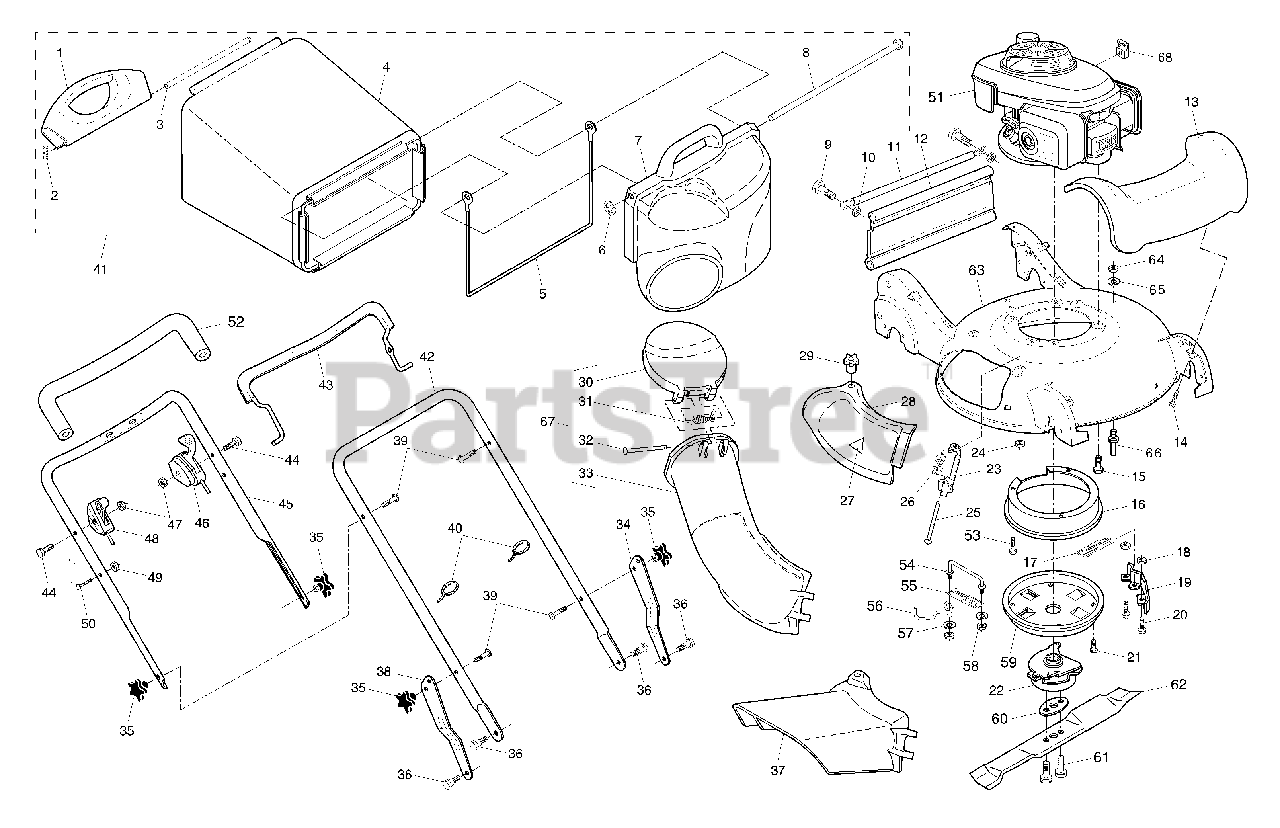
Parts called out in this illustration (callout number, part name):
1	Handle, Grassbag, Rear
2	Hairpin Cotter
3	Rod, Rear Handle, Grassbag
4	Grassbag
5	Frame, Grassbag
7	Door, Grassbag
8	Rod, Pivot
10	Nut, Hex
11	Tube, Rear Skirt
12	Skirt, Rear
13	Cover, Front
14	Screw, Hex Washer Head
15	Bolt, Engine Mounting
16	Belt Cover, Upper
18	Nut, Hex
19	Brake, Clutch
20	Bolt, Hex Head
21	Screw
22	Blade Brake / Clutch
23	Mounting Bracket, Mulcher Door
24	Nut, Hex
25	Rod, Hinge
26	Spring, Mulcher Door
27	Decal, Danger
28	Mulcher Door
30	Door, Discharge Chute
31	Spring, Door, Discharge Chute
32	Rod, Door, Discharge Chute
33	Discharge Chute, Plastic
34	Adjustment Bracket, Lower Handle, LH
35	Knob, Star
36	Bolt, Shoulder
37	Deflector, Discharge
38	Adjustment Bracket, Lower Handle, RH
39	Bolt, Handle
40	Wire Tie
41	Grassbag Assembly, Complete
42	Handle Assembly, Lower
43	Bail, Control
45	Handle Assembly, Upper
46	Blade Brake Control
48	Throttle Control
50	Rope Guide
52	Grip, Foam
53	Bolt, Engine
54	Link, Torque
56	Belt Keeper
57	Washer, Lock
59	Belt Cover, Lower
60	Spacer, Blade
61	Bolt, Hex Head
62	Blade, 21"
63	Kit, Housing
64	Nut, Hex 3/8-16
65	Washer, Lock
66	Stud, Belt Guide
67	Discharge Chute Assembly, Complete
68	Bracket, Throttle
